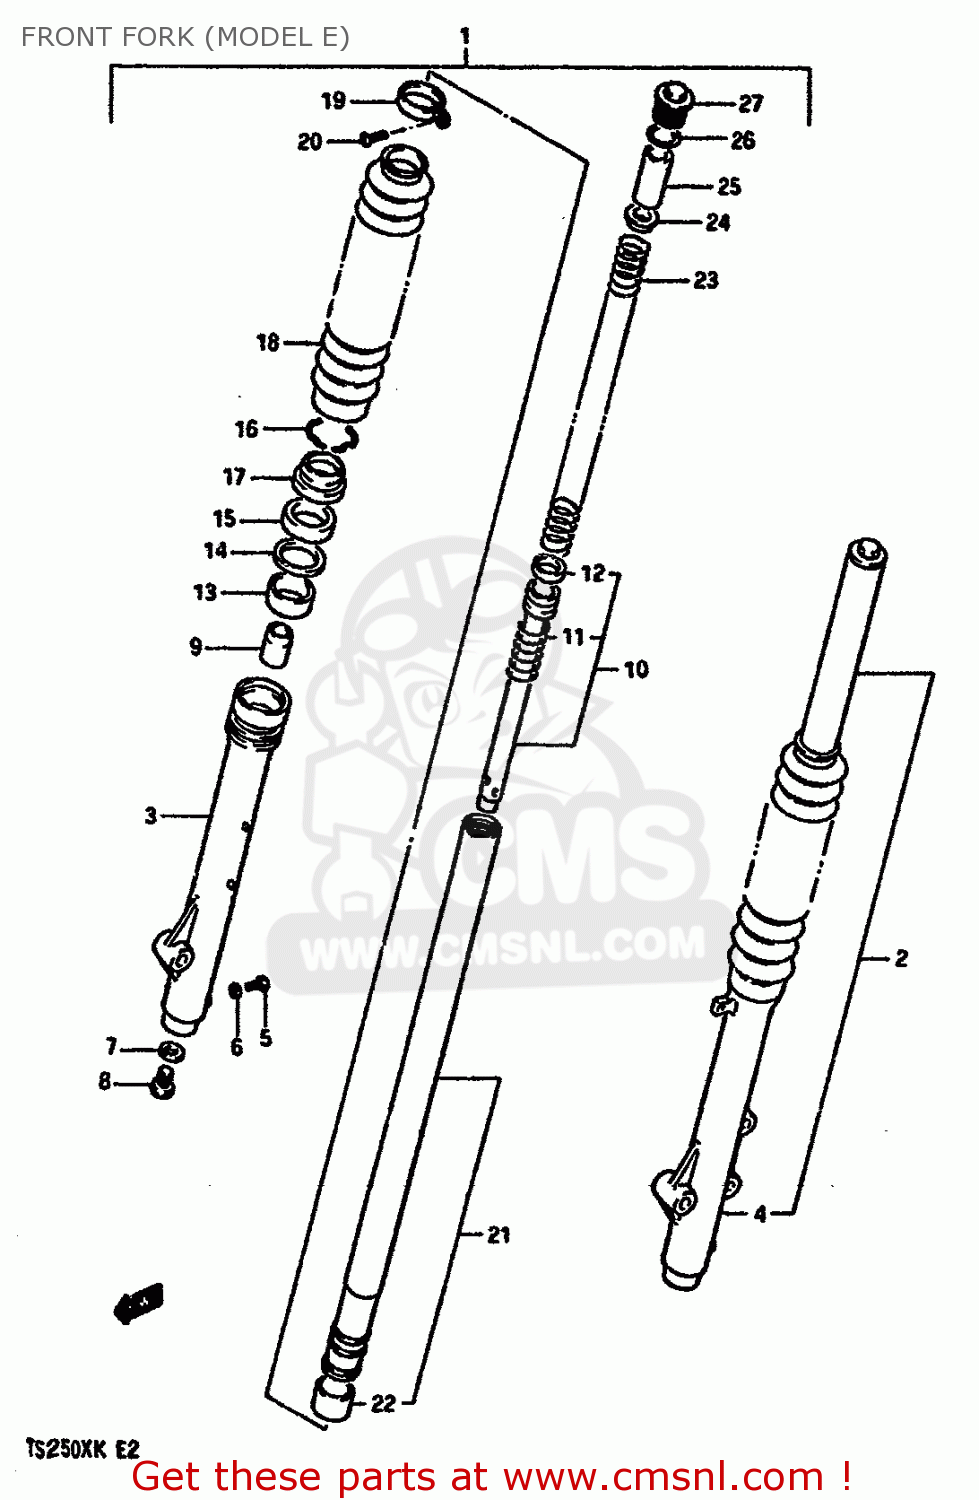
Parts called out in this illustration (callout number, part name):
1	DAMPER ASSY,RH (BLUE)
2	DAMPER ASSY,LH (BLUE)
3	OUTER TUBE,RH
4	OUTER TUBE,LH
5	SCREW
6	GASKET,DRAIN,PLUG (NAS)
7	GASKET,CYLINDER (NAS)
8	BOLT,CYLINDER
9	PIECE,FRONT FORK OIL LOCK
10	CYLINDER
11	SPRING,FORK REBOUND
12	RING,PISTON
13	METAL,SLIDE
14	WASHER(40X50X2.3)
15	SEAL,OIL
16	RING,STOPPER
17	SEAL,DUST
18	BOOT (BLUE)
19	BAND,BOOT
20	SCREW 4X10
21	INNER TUBE
22	PISTON
23	SPRING
24	GUIDE
25	SPACER,FR FORK SPRING
26	O RING
27	CAP
